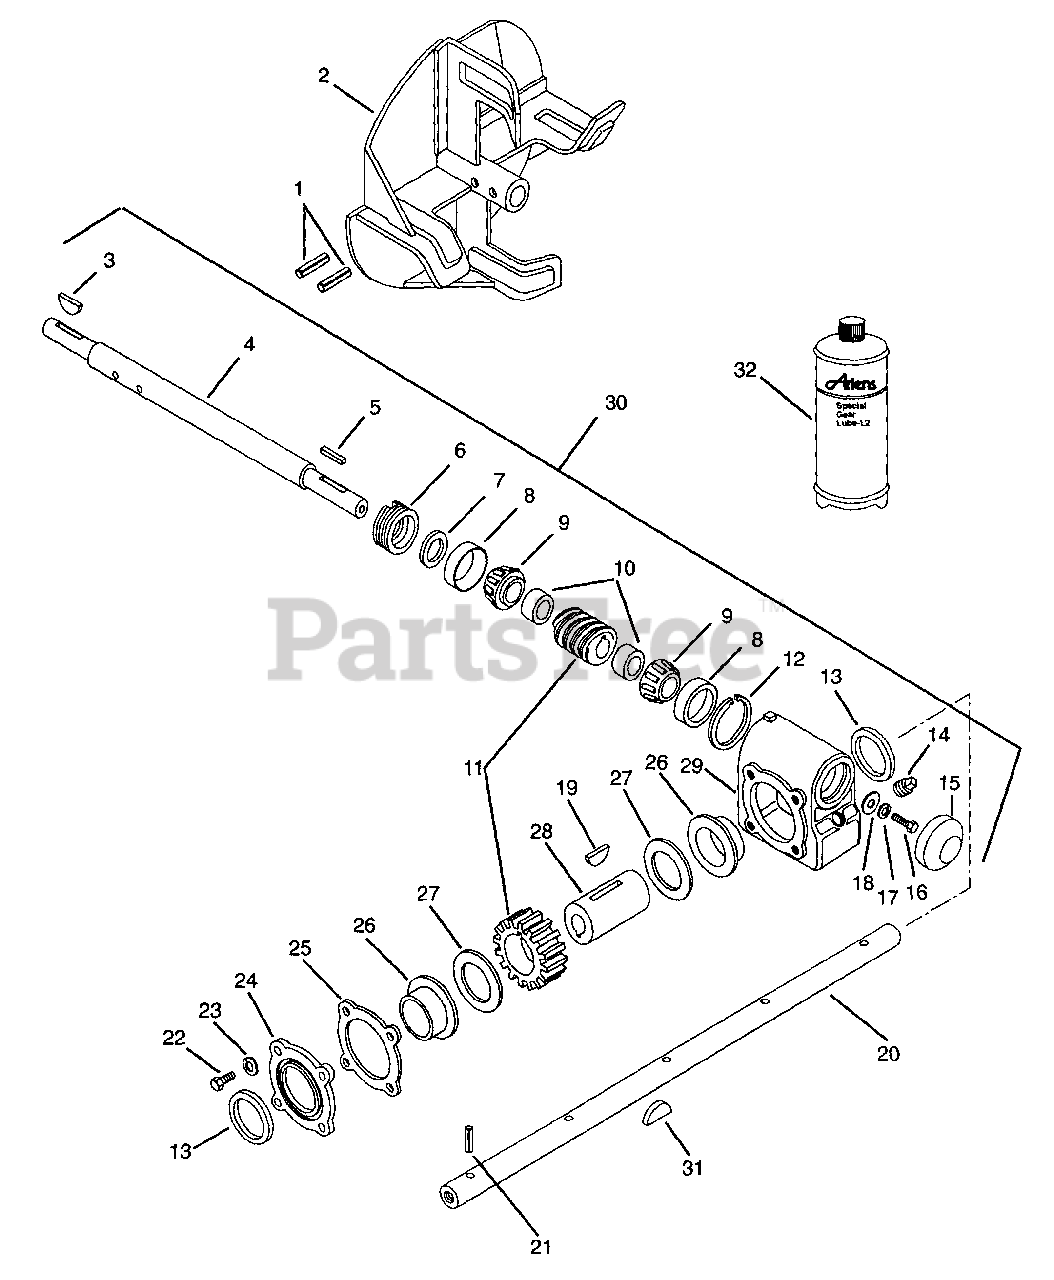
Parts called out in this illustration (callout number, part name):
1	PIN-ROLL .313X1.75
2	FAN - 14"
3	KEY-WDRF .188X.875X.375 SAE11
4	SHAFT, WORM - 1.00 DIA.
5	KEY-SQ .188X1.0X.188 SAE 8630
6	ADJUSTMENT PLUG - 1" SHAFT
7	SEAL 1.000X1.312X.150
8	BRG-CUP 1.781X.475
9	BRG-CONE .750X.61
10	BSHG, SPCR .755X1.12X.50 PM
11	WORM & GEAR SERVICE ASSEMBLY
12	RG-RTNG-INT 1.781X.062
13	SEAL 1.625X2.125X.250
14	PIPE PLUG
15	DUST CAP
16	@BLT-HEX .31-18X.75 GR5 YWZC
17	@WSHR-LK .31X.078 REG YWZC
18	WSHR-FL-STL .328X1.0X.094 YWZC
19	KEY-WDRF .25X.875X.375 SAE A
20	SHAFT, 32" RAKE - 1.00 DIA.
21	PIN-ROLL .188X1.50
22	@BLT-HEX .25-20X.75 GR5 YWZC
23	WSHR-LK-EXT. 250 ID
24	GEAR CASE COVER
26	BSHG-FLG .683X1.87X1.68X2.250
27	WSHR-FL-STL 1.625X2.500X.012
28	GEAR CASE SHAFT
29	GEAR CASE - CAST IRON
30	GEAR CASE - CAST IRON
31	KEY-WDRF .25X.875X.375 SAE A
32	ARIENS 16 OZ.BOTTLE OF L2 LUBE
